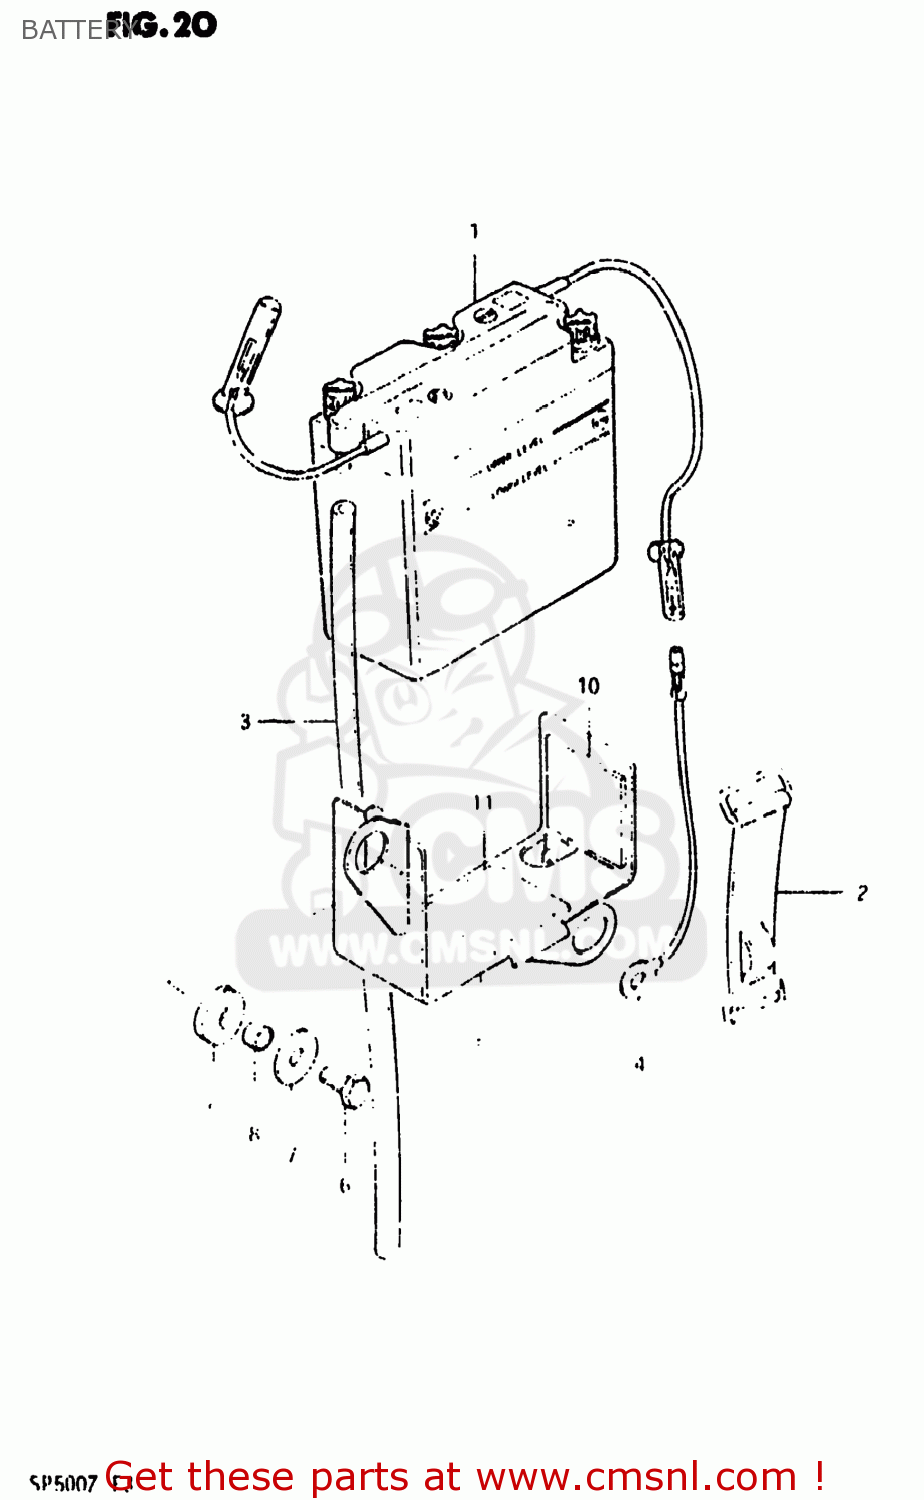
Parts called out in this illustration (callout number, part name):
1	BATTERY ASSEMBLY
2	CUSHION,BATTERY
3	HOSE,BATTERY EXHAUST
4	LEAD WIRE
5	HOLDER,BATTERY
6	BOLT, UPPER
7	WASHER (6.5X20X1.2)
8	SPACER(6.1X9X7.5)
9	CUSHION
10	PROTECTOR,BATTERY
11	PROTECTOR,BATTERY
